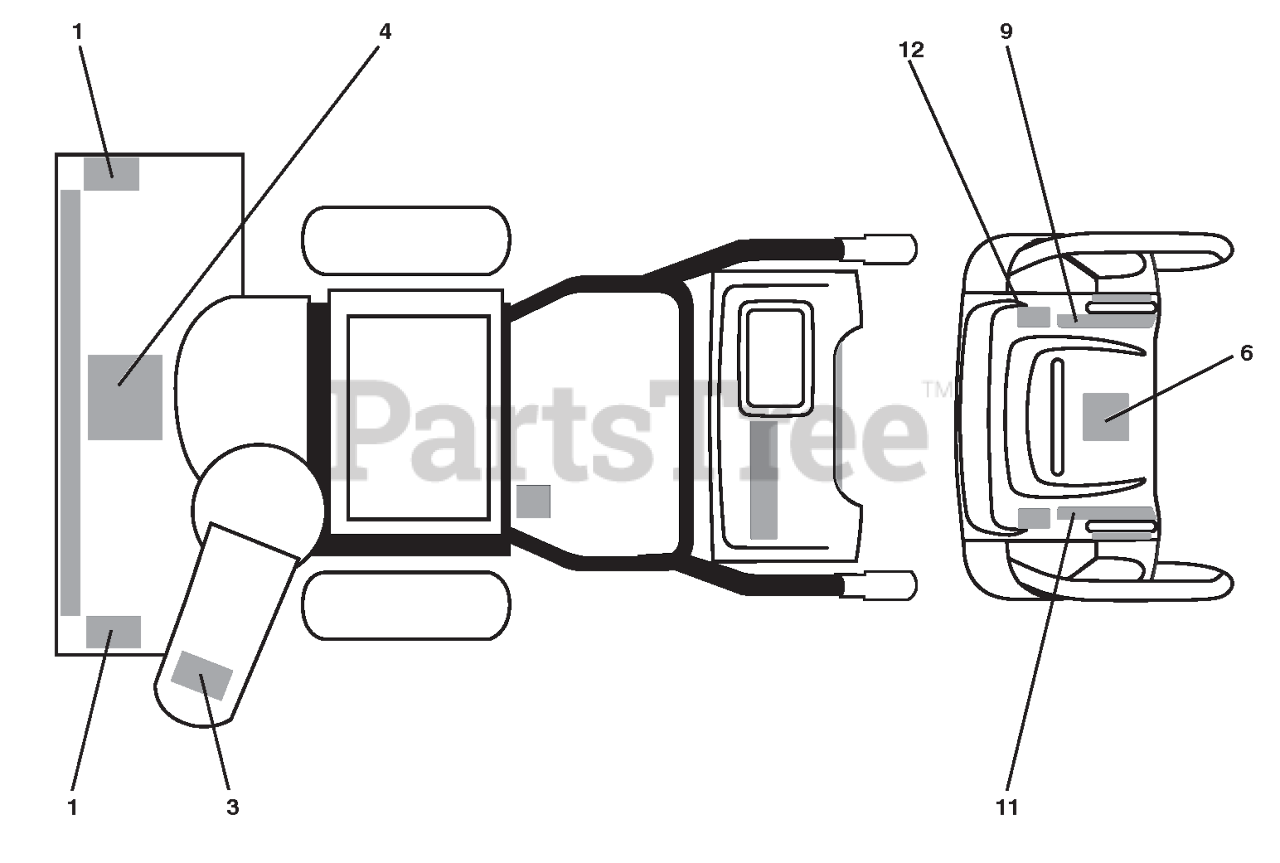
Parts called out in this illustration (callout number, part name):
1	DECAL.SNOWTHR.AUGER
3	DECAL.SNOWTHR.CHUTE.SAFETY
4	DECAL.SNOWTR.READ.OWN.MAN.E/F
6	DECAL.CONSOLE.SNOW.INST.ENG/FR
9	DECAL.CONS.RH.INST.GRY
11	DECAL.CONS.LH.REMOTE.INST.GRY
12	DECAL.CONSOLE.HAND.WARMER
